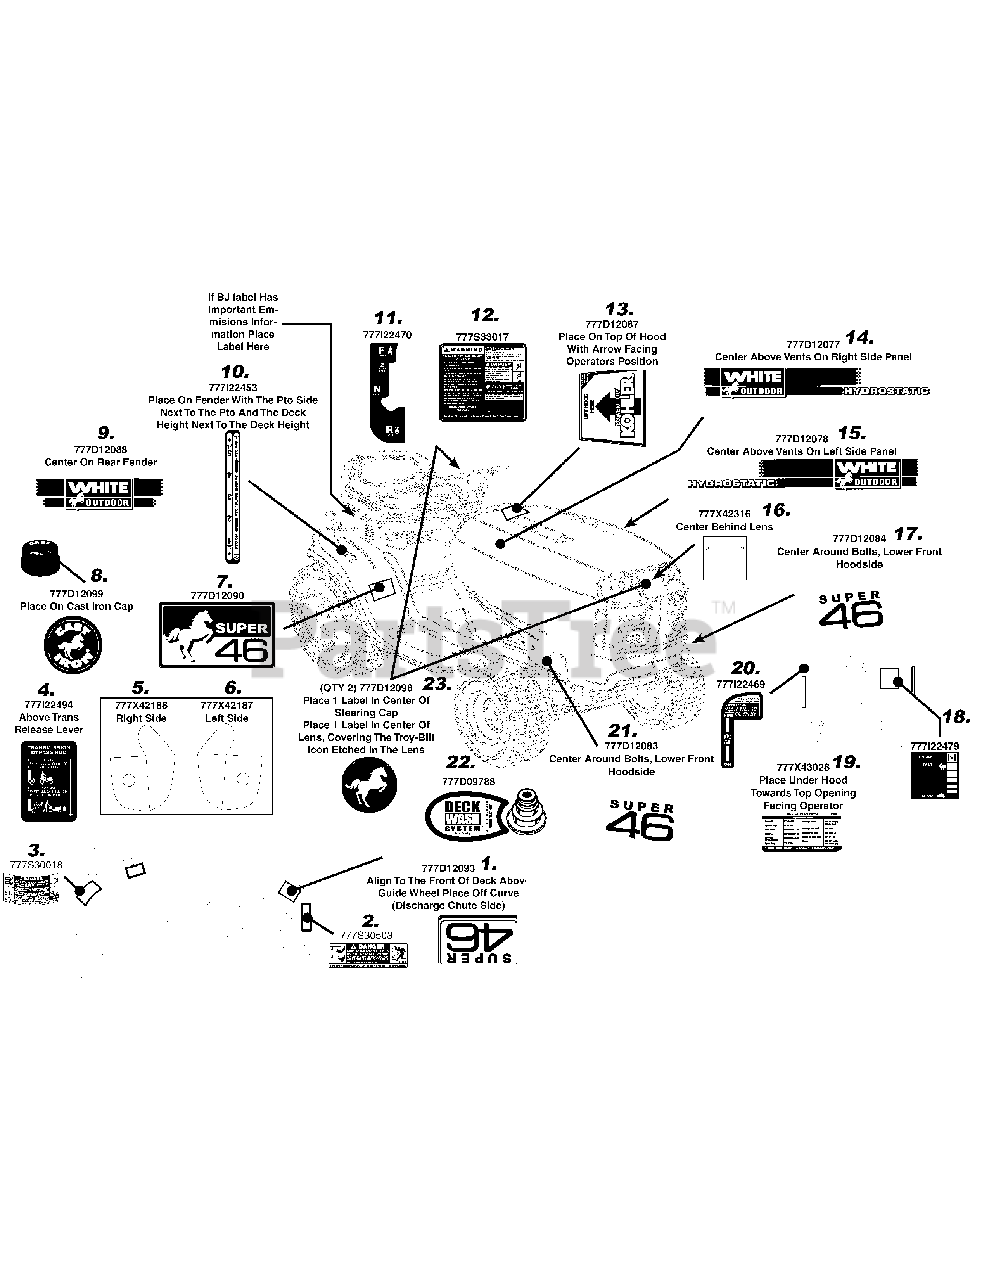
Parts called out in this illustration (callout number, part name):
1	LABEL-RIDER DECK 46" WHITE
2	LABEL-DANGER CHUTE
3	LABEL-DECK SAFETY
4	LABEL:LT-5 TRANS RELEASE
5	LABEL-RIDER T STYLE GRILL RT
6	LABEL-RIDER T STYLE GRILL LT
7	LABEL-RIDER FENDER WHITE
8	LABEL-RIDER CAST IRON CAP WHITE
9	LABEL-RIDER REAR FENDER WHITE
10	LABEL:RIDER LT-5 FENDER
11	LABEL:RIDER:LT-5 FENDER HYDRO
12	LABEL-LT 5 TRANS COVER NO OCR
13	LABEL-RIDER HOOD T KOHLER
14	LABEL-RIDER T STYLE WHITE HYDRO RH
15	LABEL-RIDER T STYLE WHITE HYDRO LH
16	LABEL-RIDER TROY MID REFL
17	LABEL-RIDER T/LOWER GRILLE LH
18	LABEL: RIDER LT-5 THRT/CHK
19	LABEL-RIDER PARTS X79TH
20	LABEL: RIDER LT-5 DASH HYDRO
21	LABEL-RIDER T/LOWER GRILLE RH
22	LABEL:RIDER:WHITE
23	LABEL-RIDER STEERING CAP WHITE
